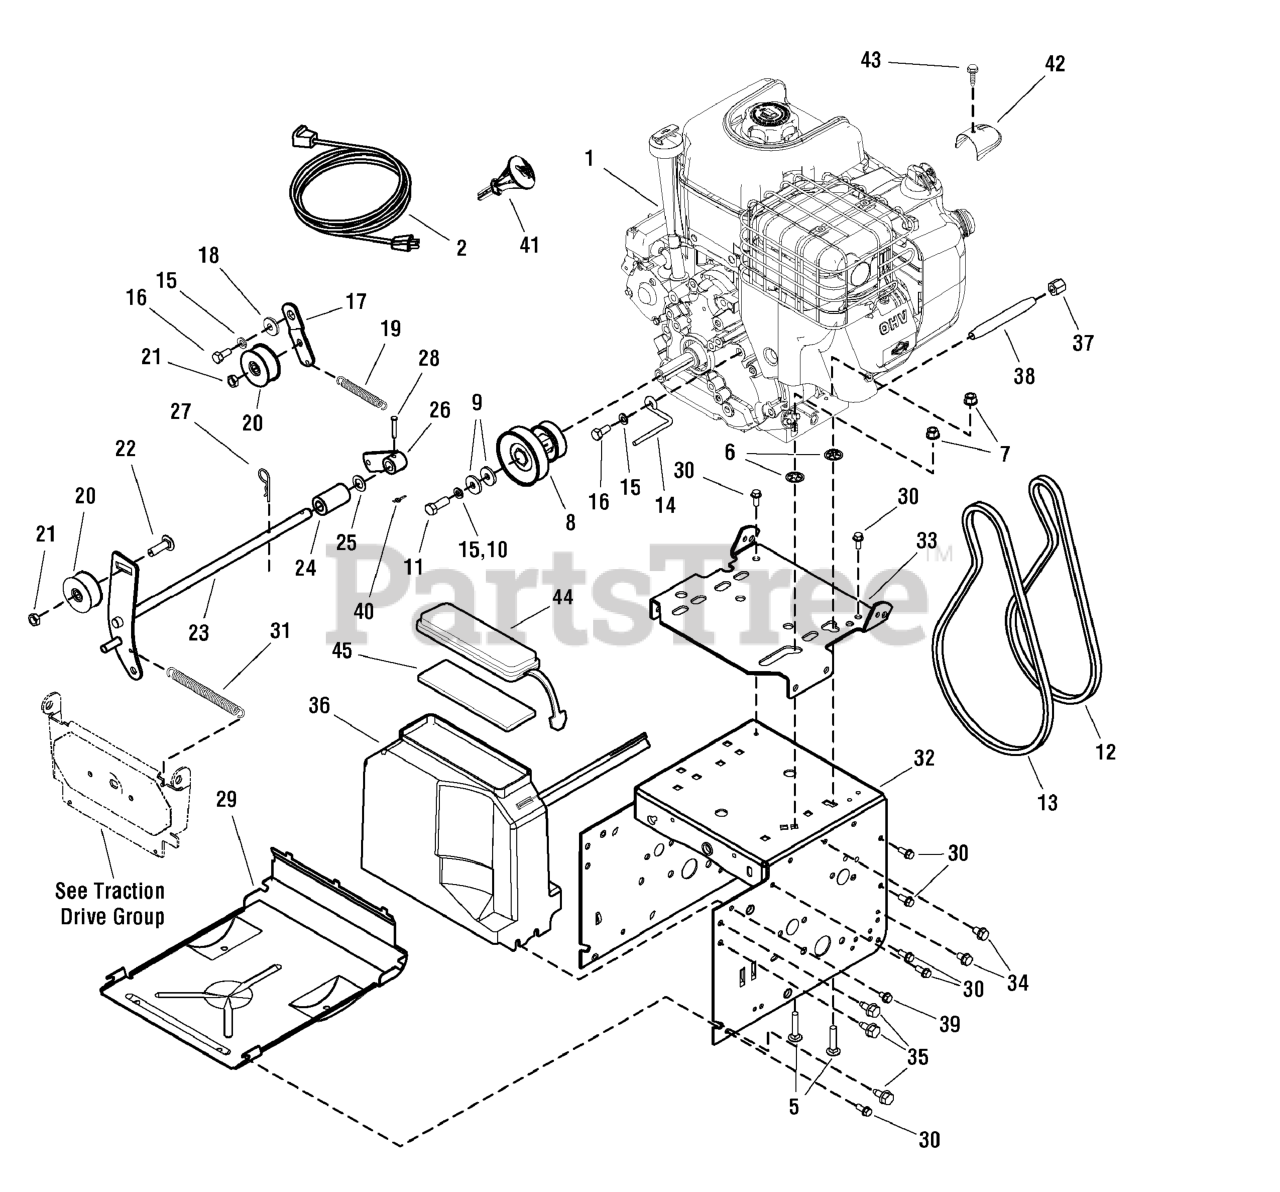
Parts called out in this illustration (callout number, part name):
2	CORD, Electric, 10FT. 110V
5	BOLT, Carriage, 5/16-18 x 1-1/2
6	NUT, Speed, 1/4
7	NUT, 5/16-18
8	PULLEY, Engine
9	WASHER, Flat, 3/8
10	WASHER, Locking, 3/8
11	CAPSCREW, Hex-Head, 3/8-24 x 1-1/4
12	V-BELT, Drive, 3L
13	V-Belt, Auger, 4L
14	GUIDE, Belt
15	WASHER, Locking, 5/16
16	BOLT, Hex-Head, 5/16-24 x 3/4
17	ASSEMBLY, Idler Bracket
18	BUSHING, Idler Bracket
19	SPRING, Extension
20	IDLER, Plastic, Ball Bearing
21	NUT, Hex-Jam, 3/8-16
22	BOLT, Carriage, 3/8-16 x 1-1/4
23	IDLER, Auger Assembly
24	SPACER, Auger Idler
25	WASHER, Flat, 1/2
26	ASSEMBLY, Spring Attachment
27	PIN, Hair
28	PIN, Clevis
29	PANEL, Bottom
30	SCREW, 1/4-20 x 5/8
31	SPRING, Extension
32	FRAME, Steerable
33	ENGINE MOUNT
34	SCREW, 3/8-18 x 1/2
35	SCREW, 3/8-18 x 3/4
36	COVER, Belt
37	CAP, Pipe
38	PIPE, Oil Drain
39	SCREW, Hex-Washer, 1/4 x 3/4, Self-Tapping
40	PIN, Cotter, 1/4, Self-Locking
41	KEY, Ignition
42	DEFLECTOR, Muffler
44	LID, Toolbox
45	PAD, Faom
